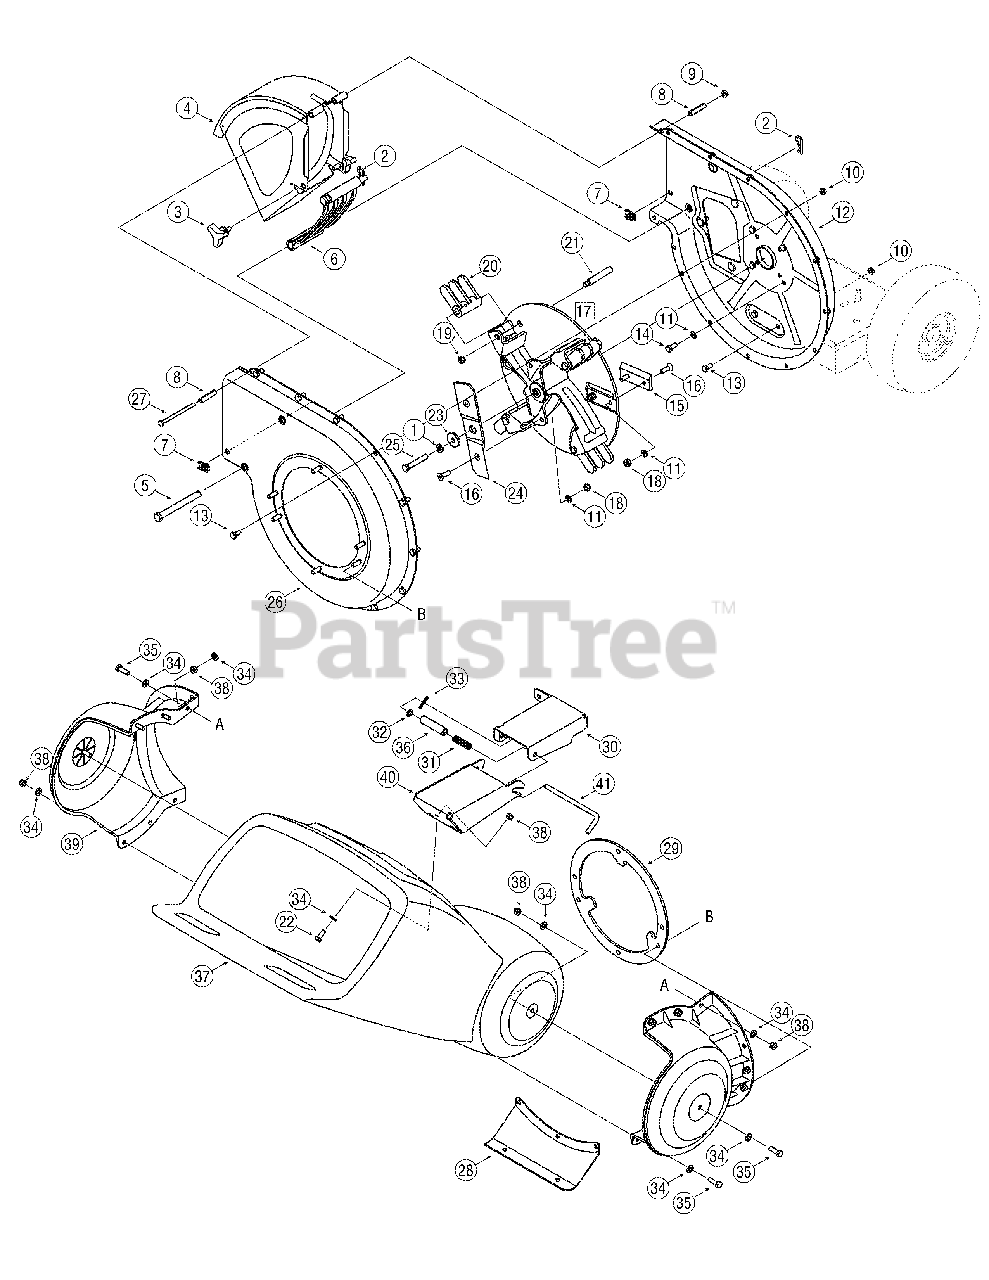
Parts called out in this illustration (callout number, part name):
1	Lock Washer, 3/8
2	Cotter Pin
3	Wing Knob 5/16-18
4	Chute Deflector Assembly
5	Clevis Pin
6	Shredder Screen
7	U-Nut 5/16-18
8	Spacer
9	Hex Lock Nut, 1/4-20
10	Hex Lock Nut 5/16-18
11	Lock Washer 5/16
12	Inner Impeller Housing Assembly
13	Hex Cap Screw 5/16-18 x.625
14	Hex Cap Screw 5/16-24 x.75
15	Chipper Blade
16	Hex Cap Screw 5/16-24 x 1.0
17	Impeller Assembly
18	Hex Lock Nut 5/16-24
19	Nut, Jam Lock, 3/8-16
20	Flail Blade
21	Shoulder Pin, .5 x 2.625
22	Hex Cap Screw 5/16-18 x.75
23	Flat Washer 3/8 x 1.25
24	Shredder Blade
25	Hex Cap Screw 3/8-24 x 2.25
26	Outer Impeller Housing Assembly
27	Hex Cap Screw 1/4-20 x 3.75
28	Front Support Bracket
29	Shredder Plate
30	Rear Hopper Bracket Assembly
31	Compression Spring 1.75
32	Flat Washer
33	Cotter Pin
34	Flat Washer.330 ID x.630 OD
35	Hex Cap Screw 5/16-18 x 1.0
36	Spacer,.375 ID x 2.50 LG
37	Hopper Assembly
38	Hex Lock Nut 5/16-18
39	Hopper Collar
40	Front Hopper Bracket Assembly
41	Lock Rod
